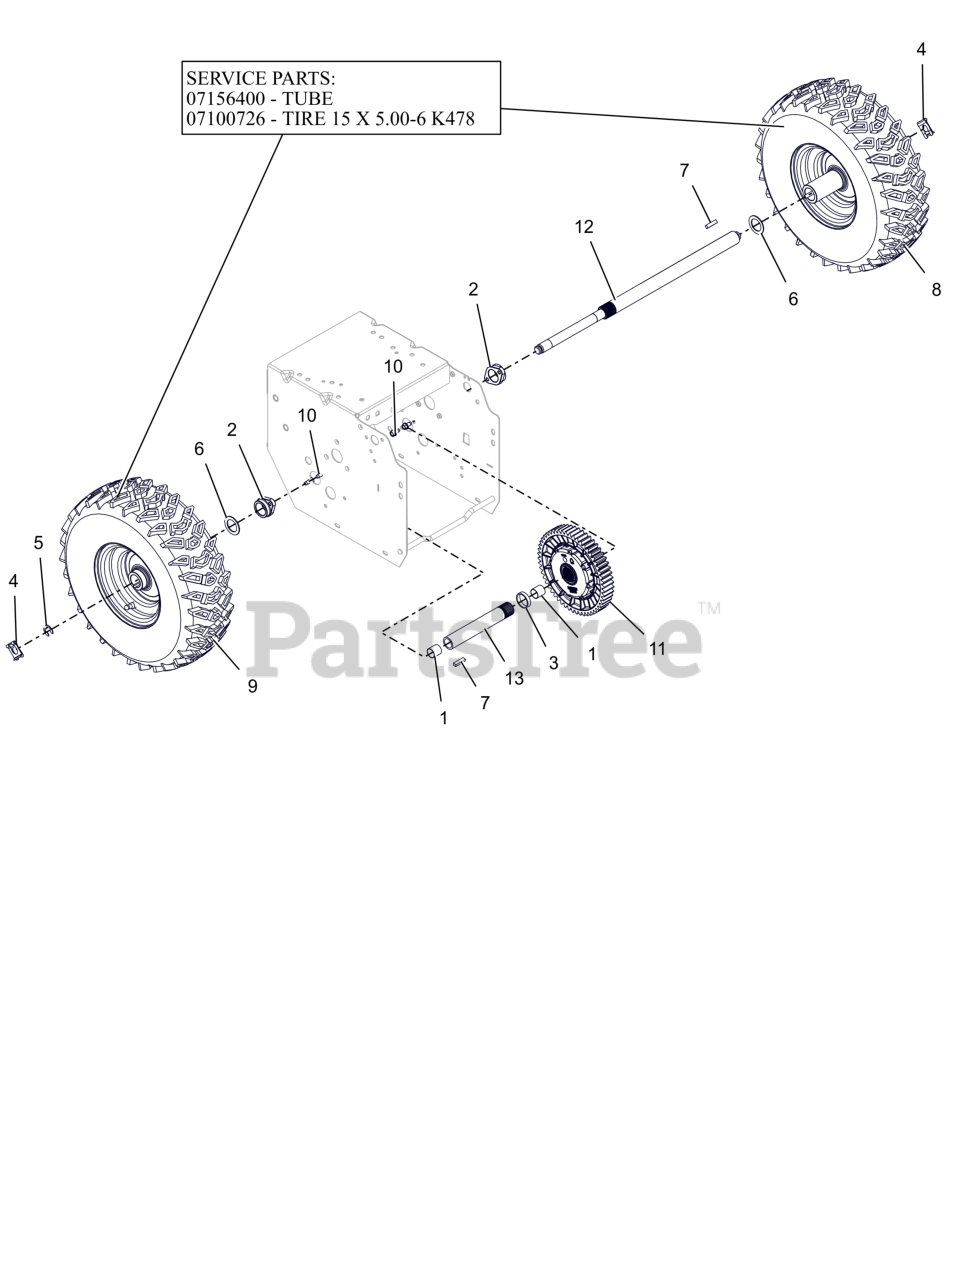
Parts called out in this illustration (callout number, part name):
1	BSHG-SLV .706X.764X.75 BRZ
2	BSHG, AXLE 1.000X1.380X.650
3	BSHG, SLV 1.062X1.228X.268
4	CLIP, SNAP .625 DIA
5	RG-RTNG-EXT .625X.042
6	WSHR, FLT 1.010X1.505X.062 ZCC
7	KEY-RECT .25X.188X1.00
8	TIRE/WHEEL, LH 15X5-6 REMOTE
9	TIRE/WHEEL, RH 15X5-6 REMOTE
10	SCR-TAP .25-20X.50 HWH ZCC
11	DIFFERENTIAL, AUTOMATIC
12	AXLE, LONG - COMPACT AUTO DIFF
13	AXLE, SHORT - W/BUSHINGS
